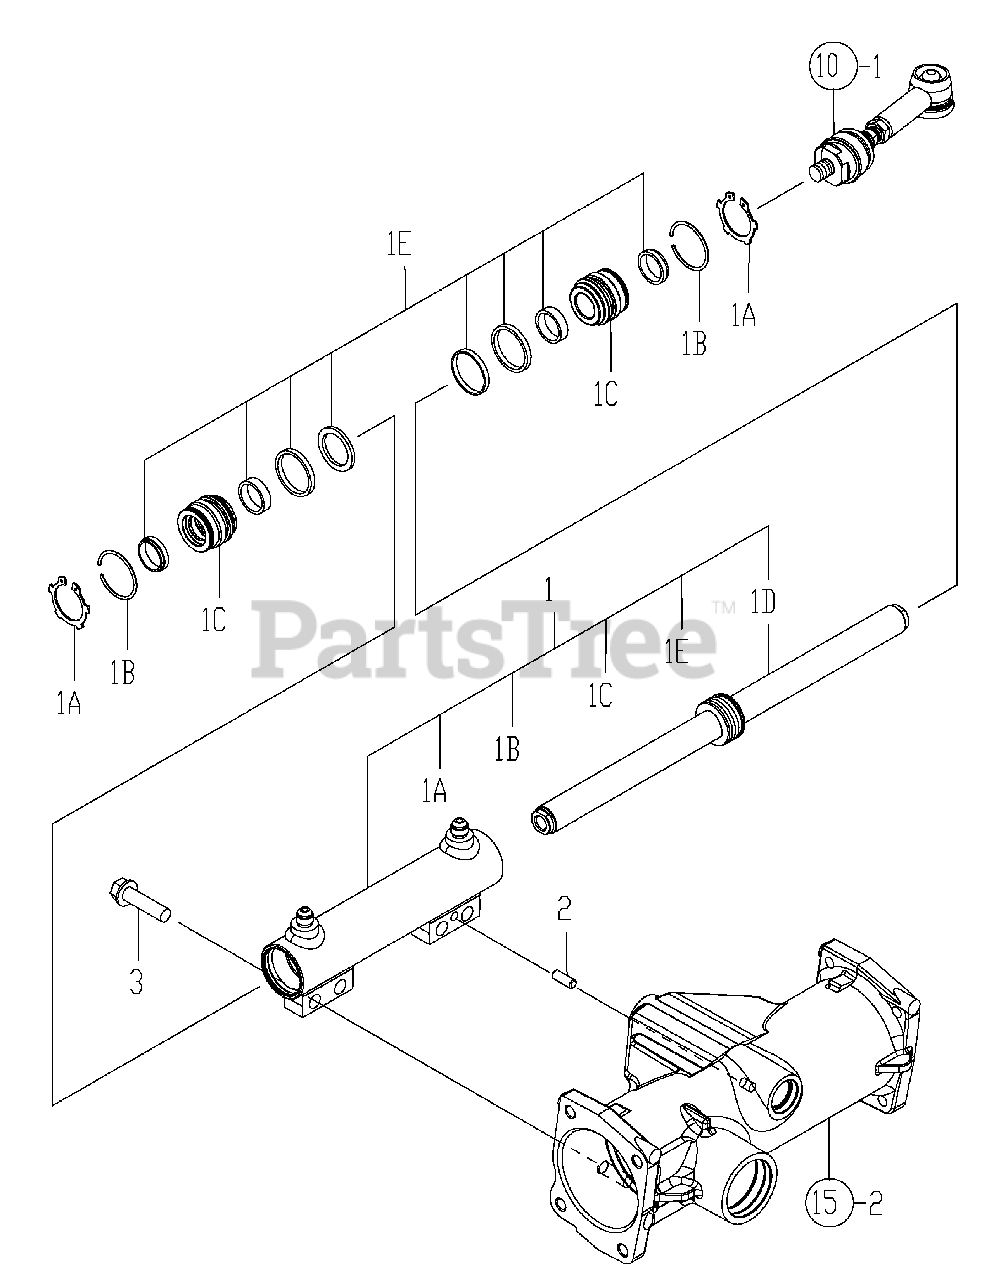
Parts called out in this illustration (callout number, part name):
1	CYLINDER ASSY, PST (11.5 MM)
1	CYLINDER ASSY, PST (12.5 MM)
1B	RETAINING RING
1E	SEAL KIT (11.5 MM)
1E	SEAL KIT (12.5 MM)
